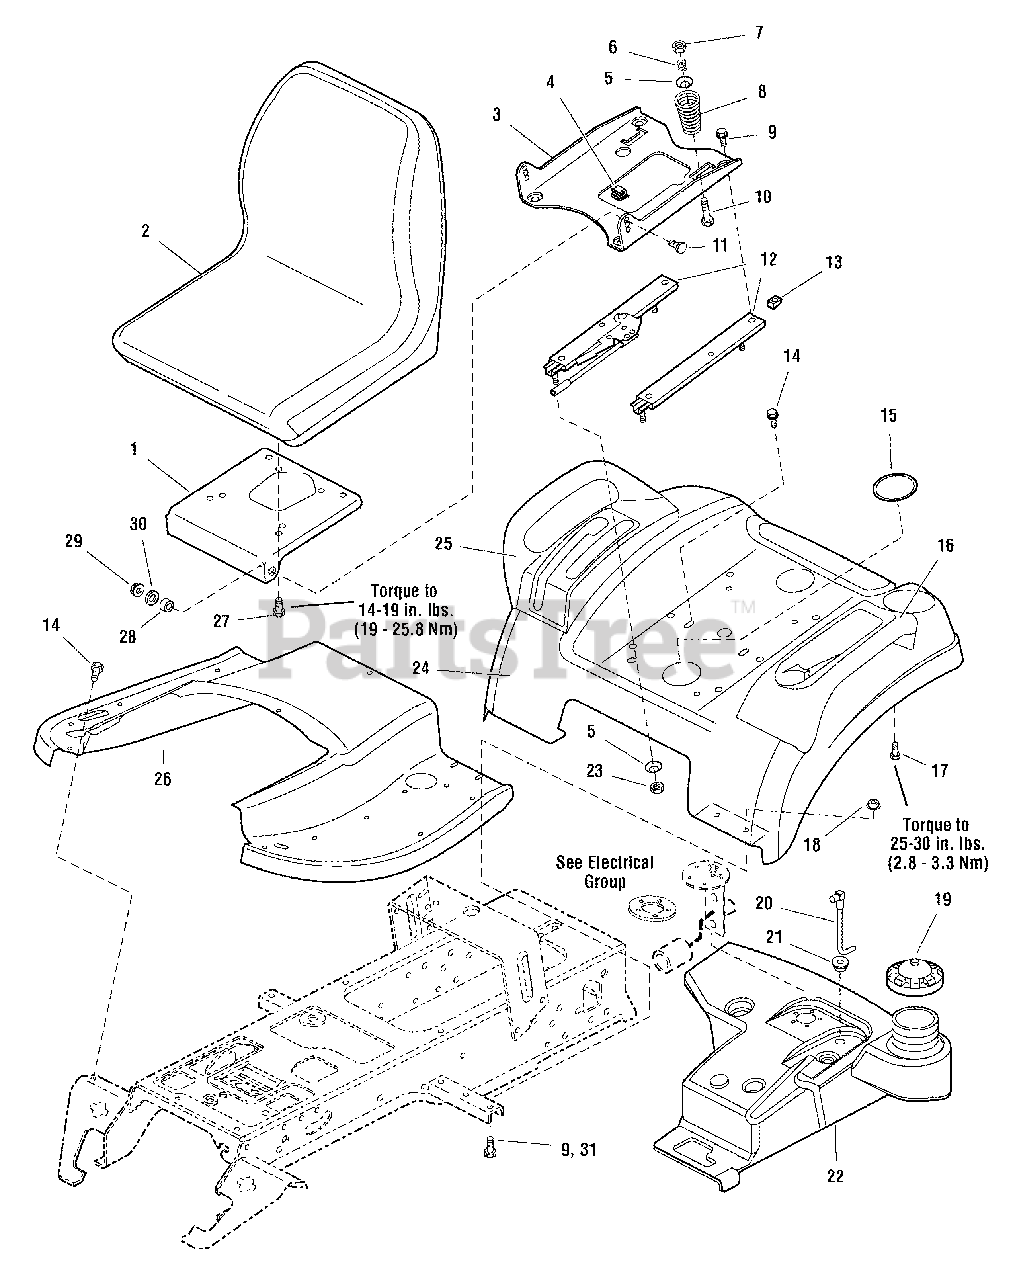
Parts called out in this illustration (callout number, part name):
1	BRACKET, 1-5/8 x 1-3/4
2	SEAT, 18" Back
3	SUPPORT, Seat
5	WASHER, Spring, 5/16 x 1 1/4
6	SPRING, Compression
7	NUT, Hex Lock, ESNA Light, 5/16-18
8	SPRING, Compression
9	CAPSCREW, Hex Flange Whiz Lock, 5/16-18 x 3/4
10	BOLT, Carriage, 5/16-18 x 2
11	BOLT, Carriage, 3/8-16 x 1
12	SLIDE, Seat
13	NUT, Speed, Lug Type, 5/16-18
14	CAPSCREW, Hex Washer Head Taptite, 5/16-18 x 5/8
15	PLUG, Plastic
16	POD, with Cup Holder, LH
17	SCREW, Conical Washer, 1/4-20 x 7/8 Dog Point
18	NUT, Hex Flange Whiz Lock, 5/16-18
19	CAP, Gas
20	TUBE & ELBOW ASSEMBLY
21	BUSHING, 3/8 x 9/16 x 5/8, Rubber
23	NUT, Hex KEPS, 5/16-18
24	DECK, Seat, Orange
24	DECK, Seat, Red
25	POD, RH with 2 Slots
26	TUNNEL, Orange
26	TUNNEL, Red
27	CAPSCREW, Hex Flange Whiz Lock Dog Point, 5/16-18 x 1
28	SPACER, 25/64 x 5/8 x 3/16
29	NUT, Hex Flange Two-Way Lock, 3/8-16
30	WASHER, 3/8
31	CAPSCREW, Taptite 5/16-18 x 1-1/4
